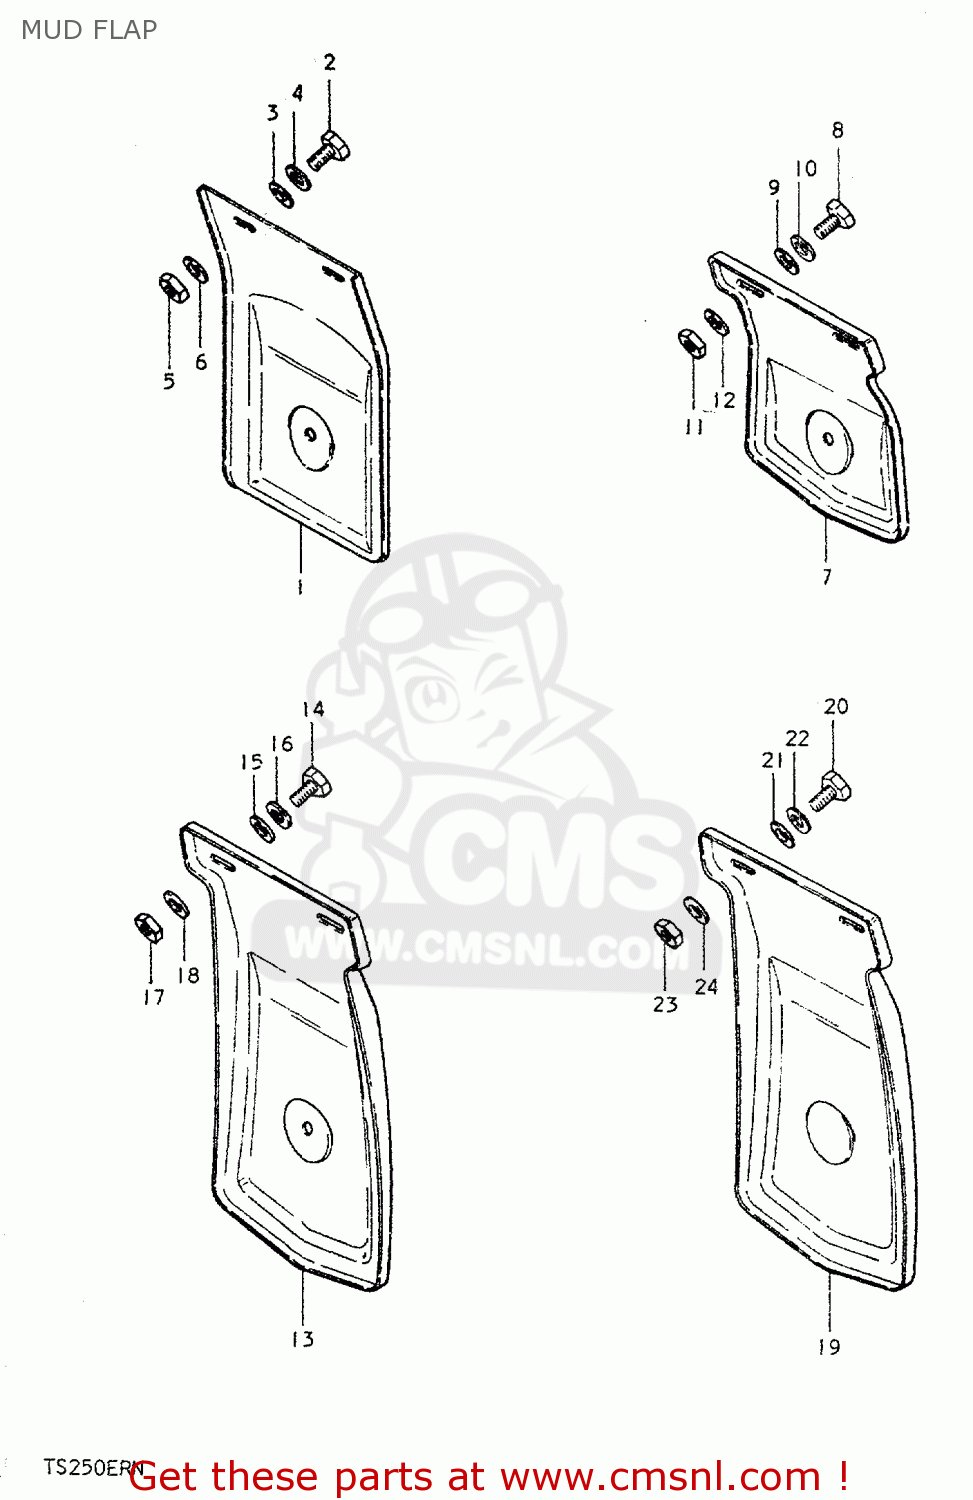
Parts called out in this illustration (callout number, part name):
1	FLAP,RR FENDER MUD
2	BOLT, UPPER
3	WASHER
4	LOCK WASHER
5	NUT
6	WASHER
7	MUD GUARD,REAR FENDER
8	BOLT, UPPER
9	WASHER
10	LOCK WASHER
11	NUT
12	WASHER
